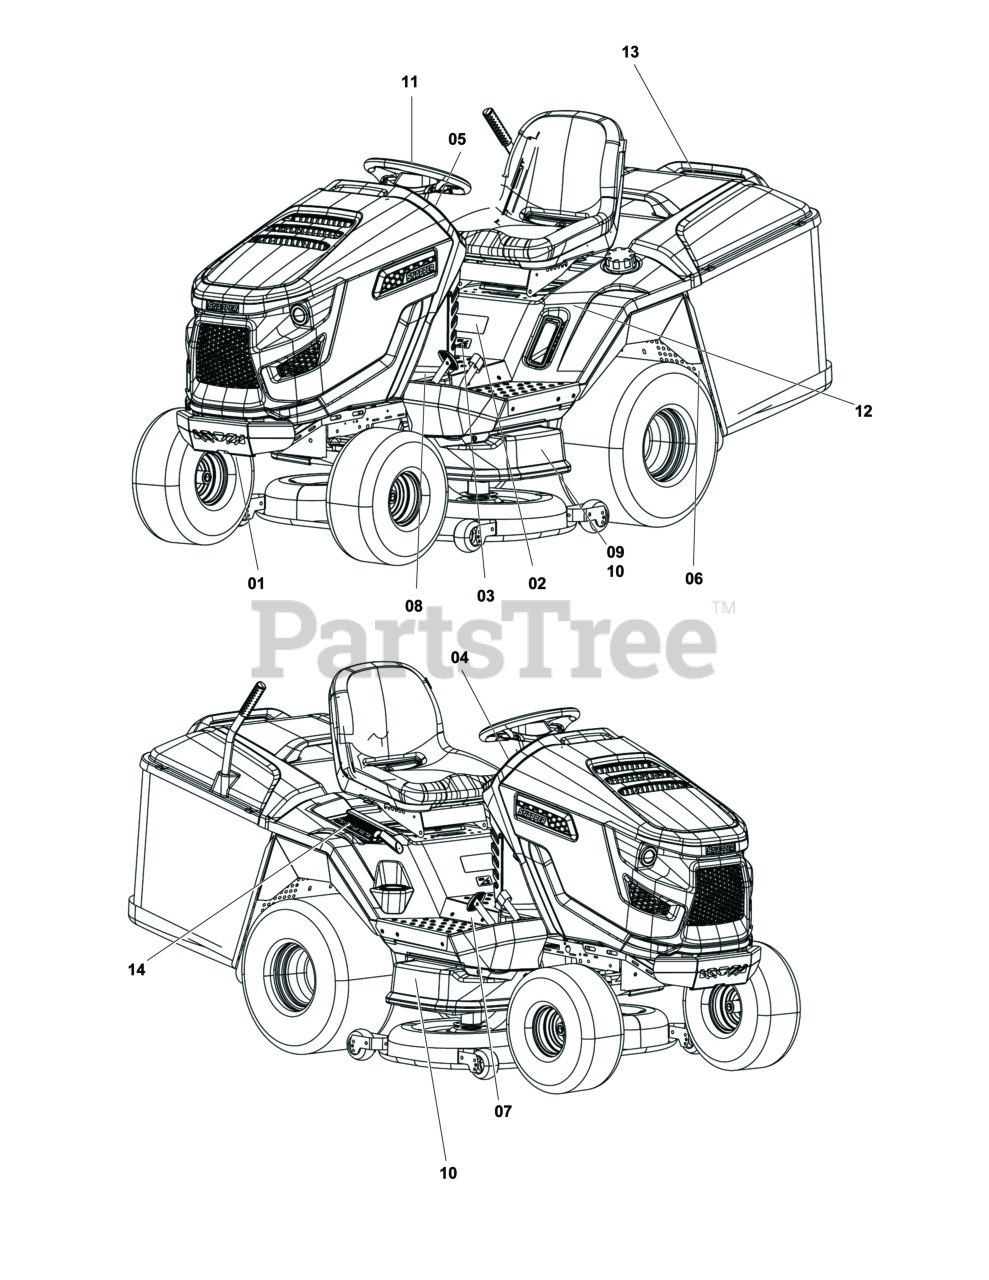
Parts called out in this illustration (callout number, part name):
04	DECAL, Dash, RH, RPX
05	DECAL, Dash, LH, RPX
11	DECAL, Brand
12	DECAL, Model
13	DECAL, Brand
14	DECAL, Cutting Height
